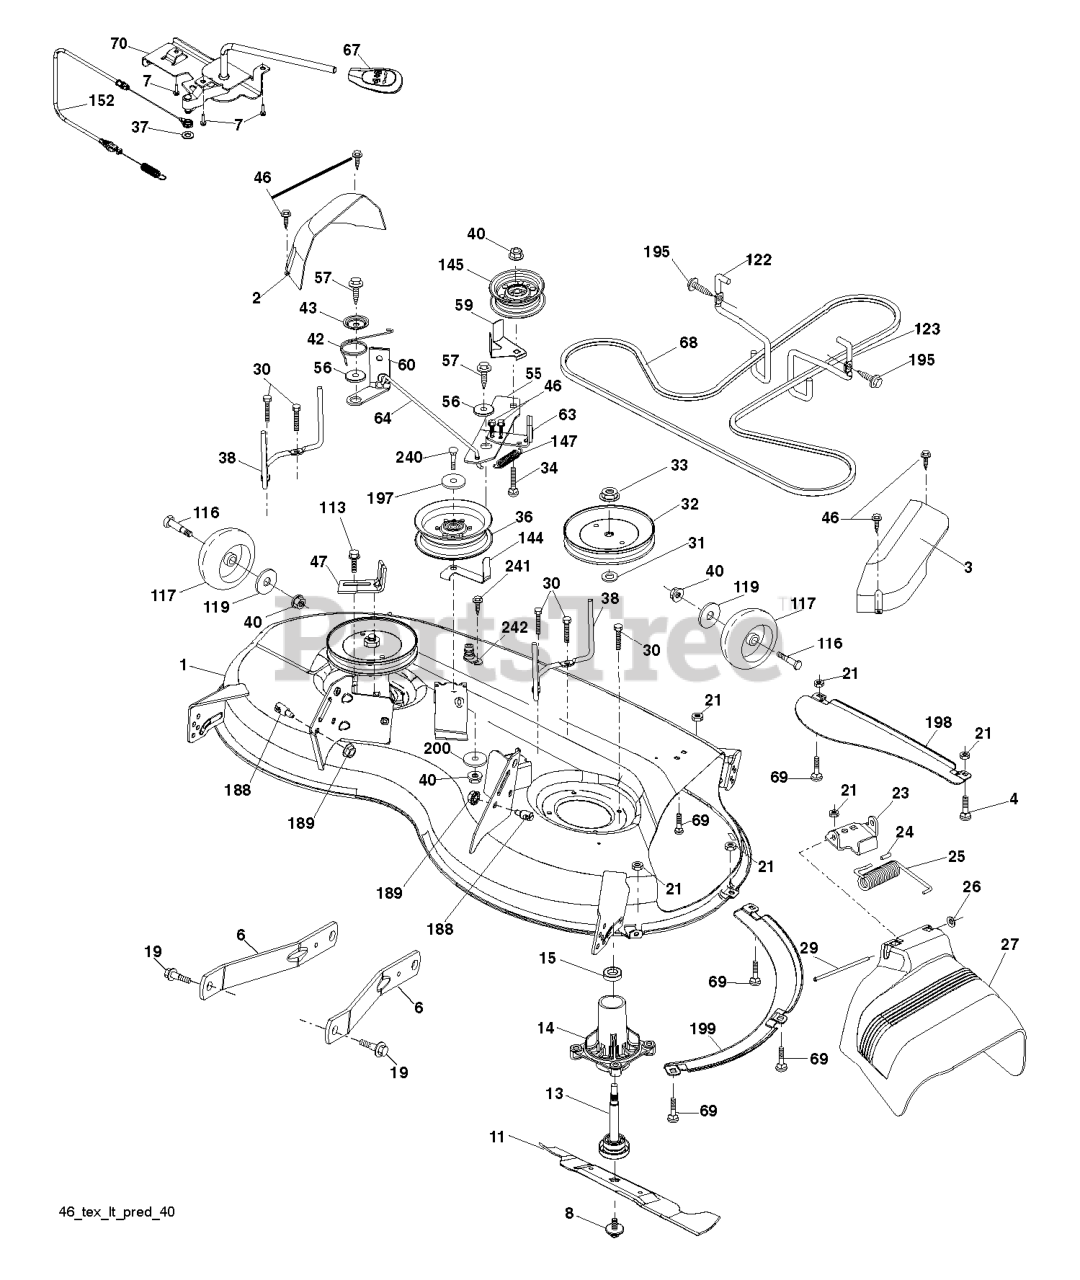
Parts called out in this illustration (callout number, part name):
1	DECK.WELDMENT.46.2GA.WHLS.GRAY
2	COVER.MANDREL.LH.46"
3	COVER.MANDREL.RH.46"
4	BOLT
6	ARM.SUSPENSION.MOWER.R
7	SCREW.#10 X 0.750.BOS
8	BOLT.WASHER.ASM.7/16-2
11	BLADE.MOWER.46".HI.LIFT
13	SHAFT.ASM.MDRL.N/GREASE.38
14	RP.HOUSING.MANDREL.4PT.
19	BOLT.SHOULDER
21	LOCKNUT
23	BRKT.DEFLECTOR.38"2005+
24	CAP-SLEEVE LT
25	SPRING.TORSION.DEFLECT
26	NUT PUSH M
27	SHIELD.DEFLECTOR.MOWER.46"BLAC
29	ROD.HINGE
30	SCREW, WASHER HEAD
31	WASHER.SPACER.MANDREL
32	PULLEY.MANDREL.5.438.PD
33	NUT.FLANGE.LOCK.TOP
34	BOLT.3/8-16X1.50
36	PULLEY.IDLER.2006
37	WASHER
38	KEEPER.BELT.MANDREL.PULLEY
40	NUT LOCK FLG 3/8-16 UNC
42	SPRING.TORSION.BRAKE
43	SRPING.TORSION.RETAINE
46	SCREW.1/4-20X5/8
47	BRKT.CLUTCH.CABLE
56	SPACER.RETAINER
57	SCREW 3/8-16X1
59	GUARD, BELT
60	ARM BRAKE MOWER RH 38"
63	ARM BRAKE MOWER
64	LINKAGE BRAKE
67	HANDLE.CLUTCH.CABLE.LT
68	V-BELT
69	BOLT
70	CLUTCH.ASM.MANUAL.YT.PREDATORQ
113	BOLT.5/16HEX.WHS.HD
116	BOLT.SHOULDER.3/8-16X3-5/8.
117	RP WHEEL. GUAGE RALLY
119	WASHER
122	KEEPER BELT ENGINE LH
123	KEEPER BELT RH
144	KEEPER.BELT.MOWER
145	PULLEY.IDLER.48"PRIMARY
147	SPRING RETURN
152	CABLE.MECHANICAL.CLUTCH
188	STUD.FASTNER.W/ANTI-ROTATE
189	NUT LOCK HEX FLANGE 5/16-18
195	SCREW, 3/8-16X3/4
197	WASHER
198	BAFFLE CENTER FRONT
199	BAFFLE FRONT RH
200	WASHER.13/32 X 1 X 1/2.11GUARD
240	BOLT-HEX EAK
241	SCREW.TT.#10-32X.5.3/8.FLANGE
242	PORT.WASHOUT
